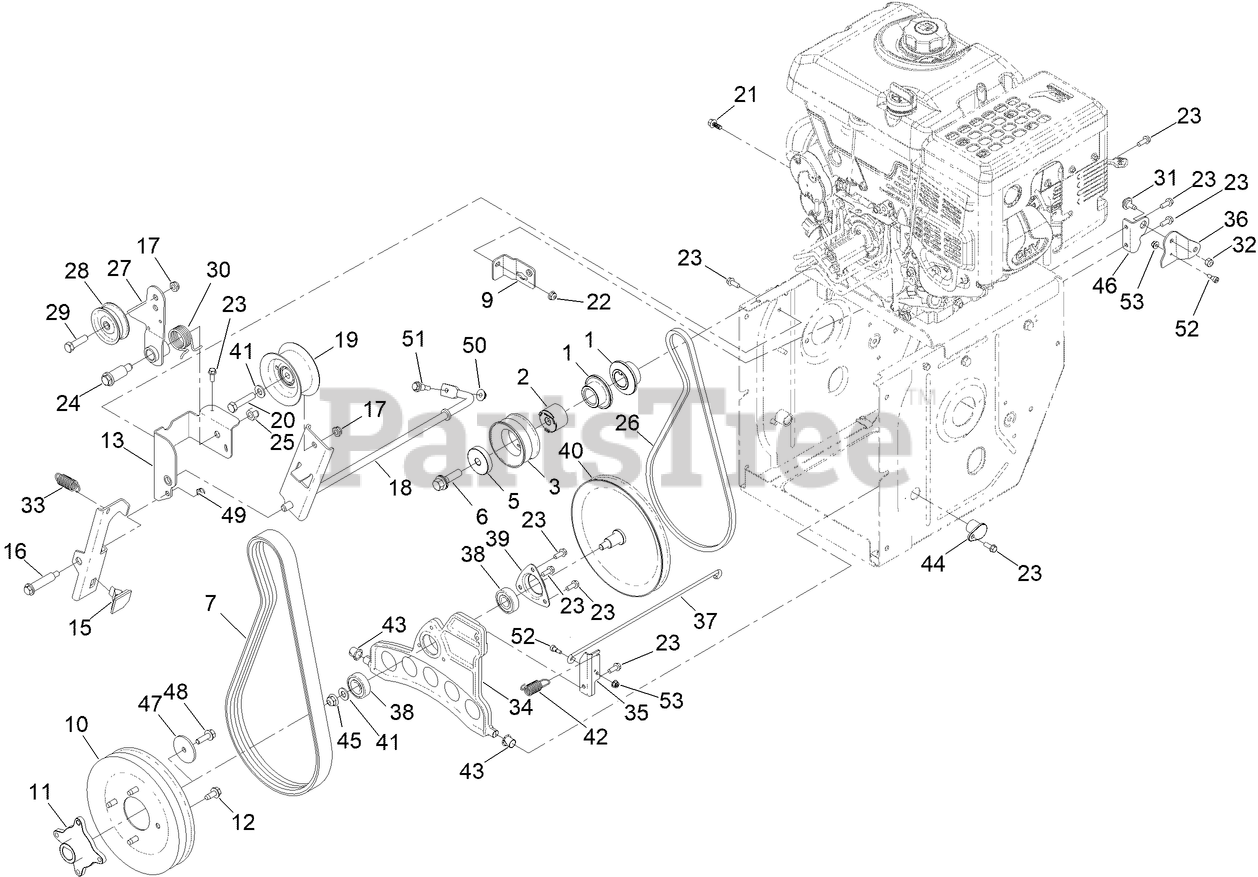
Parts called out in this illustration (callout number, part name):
1	PULLEY-TRACTION, ENGINE
2	PULLEY-SPACER
3	PULLEY-IMPELLER, DOUBLE SHEAVE
5	SUPPORT-PULLEY
6	BOLT-BLADE
7	BELT-V
9	BRACKET-CLUTCH, IMPELLER
10	PULLEY-IMPELLER, DOUBLE SHEAVE
11	HUB-PULLEY
12	SCREW-HWHTF
13	BRACKET-BRAKE, CLUTCH
15	PAD-BRAKE
16	BOLT-SHOULDER
17	NUT-HEX
18	ARM-CLUTCH, IMPELLER
19	PULLEY, IDLER
20	SCREW-HH
21	SCREW-HHF
22	NUT-HF
23	SCREW-HWH
24	BOLT-SHOULDER
25	NUT-HEX
26	V-BELT
27	ARM-IDLER, TRACTION
28	PULLEY-IDLER
29	SCREW-HH
30	SPRING-TORSION
31	SCREW-SHOULDER
32	NUT-HEX
33	SPRING-EXTENSION
34	PLATE-FRICTION, WHEEL
35	BKT-TRACTION PLATE
36	BELLCRANK-DRIVE
37	LINK-TRACTION, HD
38	BEARING-BALL
39	RETAINER-BEARING
40	PULLEY-TRACTION
41	WASHER-FLAT
42	SPRING-EXTENSION
43	BUSHING-NYLINER
44	BUSHING-PLATE, TRACTION
45	NUT-HF, NI
47	WASHER-PLAIN
48	SCREW-HHF
49	NUT-HEX
50	NUT-HF
51	BOLT-SHOULDER
52	SCREW-SHOULDER
53	NUT-HF
